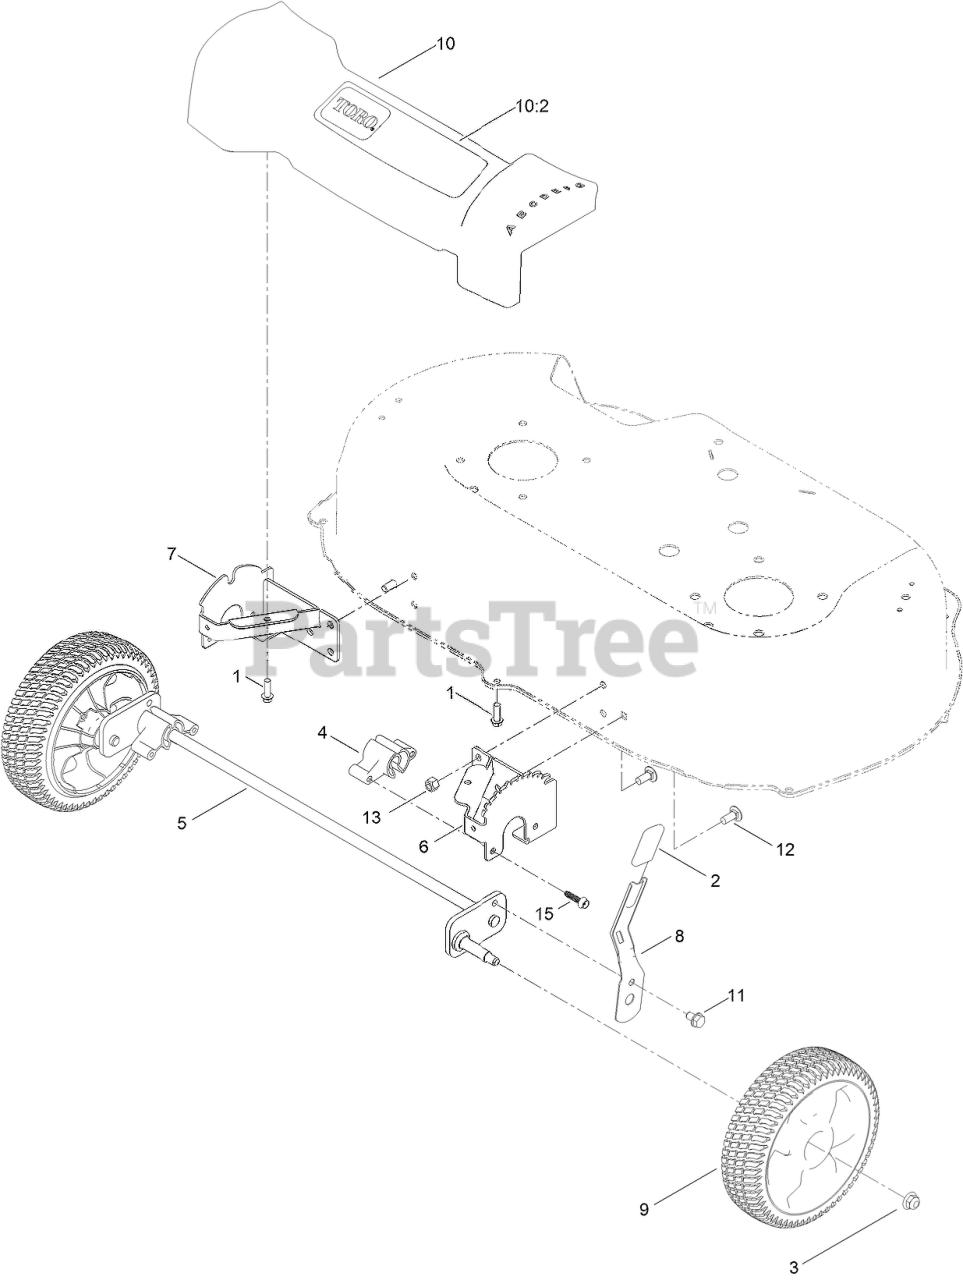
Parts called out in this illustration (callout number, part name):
1	SCREW-PLASTITE, HWH
2	GRIP-LEVER
3	NUT-HF, NI
4	BUSHING-PIVOT, FRONT
5	FRONT AXLE ASM
6	PLATE-HOC, LH
7	PLATE-HOC, RH
8	ARM-SPRING
9	8 INCH WHEEL ASM
10	FRONT COVER ASM
10:2	DECAL-COVER, FRONT
11	SCREW-HWH, THD ROLL
12	BOLT-CARR
13	NUT-HEX
15	SCREW-FLANGE, PLASTIC
